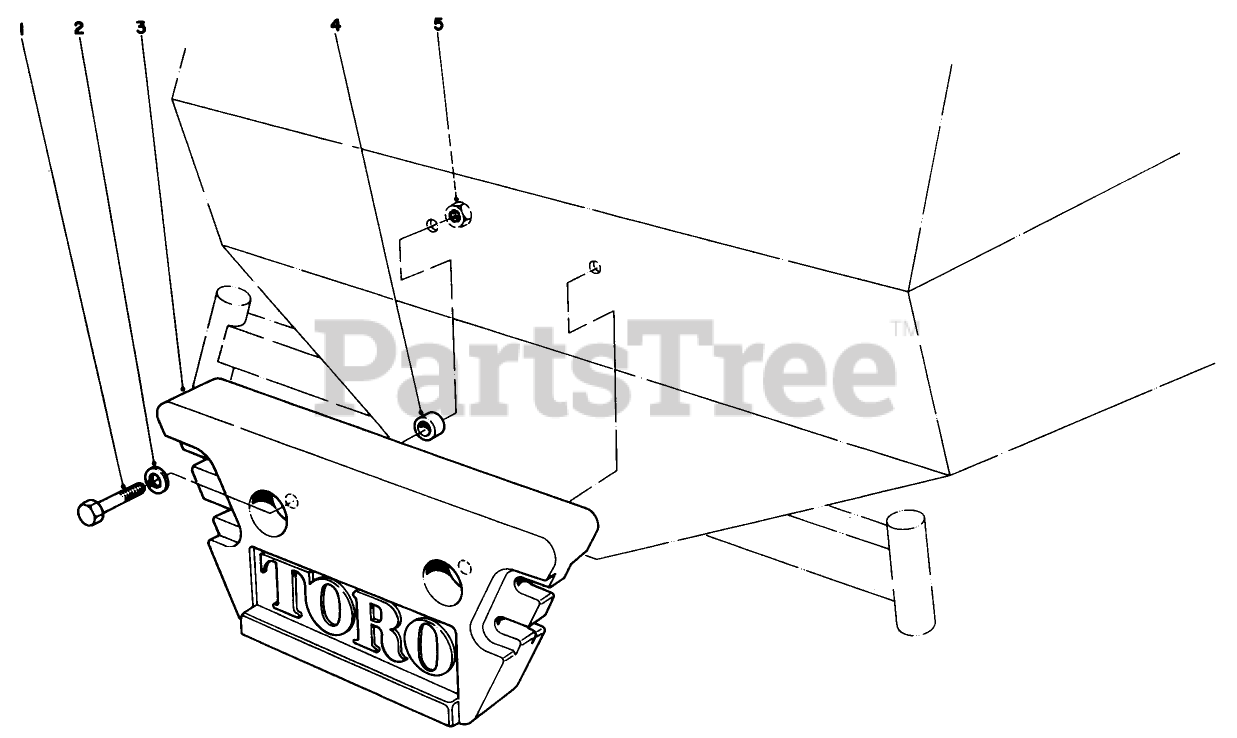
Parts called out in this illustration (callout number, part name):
1	SCREW-HH
2	SCREW-HH
4	SPRING ANCHOR BSHG
5	NUT-HH
